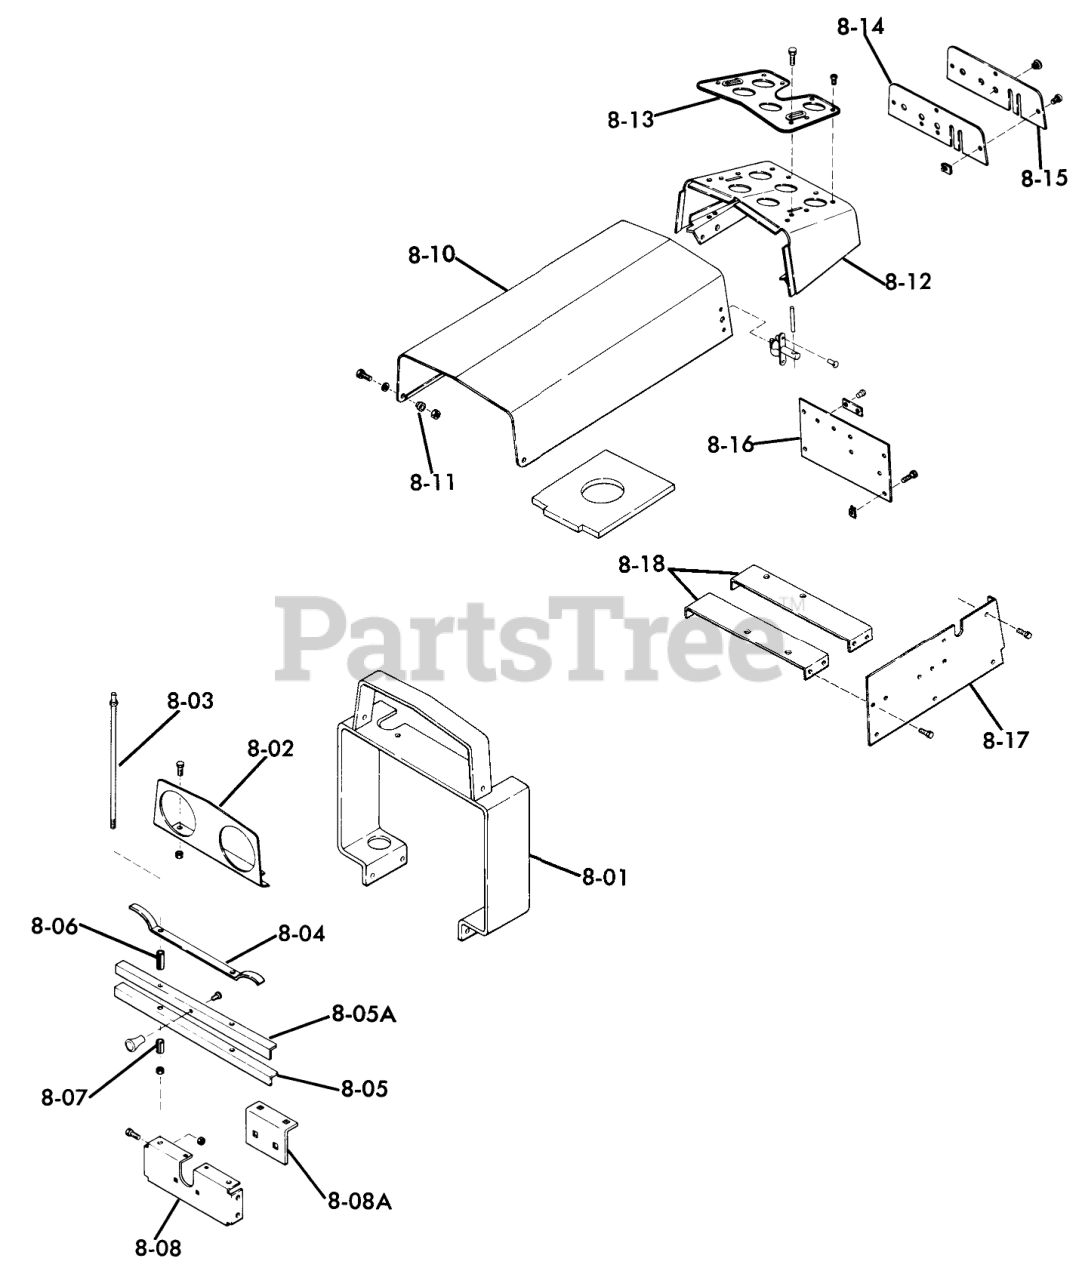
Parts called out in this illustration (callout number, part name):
8-11	WASHER 5/16 SAE
8-12	SCREW
8-15	Screw
8-15	Speed Nut
8-17	SCREW
8-18	SCREW
